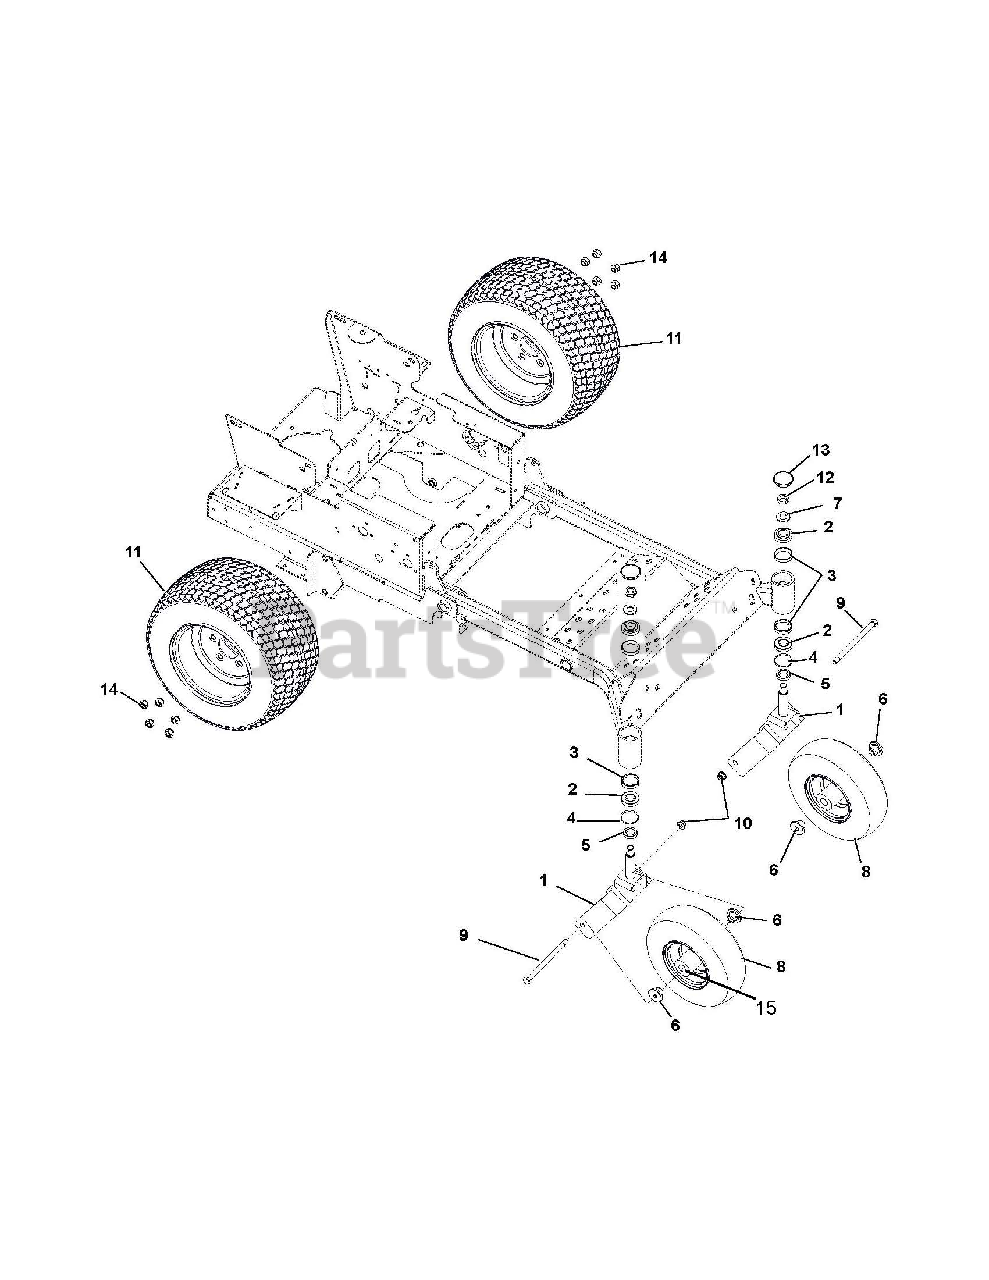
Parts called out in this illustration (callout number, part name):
1	Weldment, Front Fork
2	Bearing, Cone with Grease, 1.0 x .58
3	Bearing, Cup 1.980 x .420
4	Bearing Seal 1.5 x 2 x .18
5	Spacer, PM, 1.03 I.D. x 1.5 O.D. x .375
6	Spacer, Wheel
7	Washer, Flat, Steel .812 x 1.50 x .135
8	Tire/Wheel Assembly, 13 x 5.00-6
8	Tire/Wheel Assembly 4.80-8
9	Bolt, Hex .50-13 x 7.50 Grade 5
10	Nut, Nyloc Flange .50-13
11	Tire/Wheel Assembly, 20 x 10.00-10
11	Rim and Hub Assembly 4.10/3.50 x 6
12	Nut, Center Lock Jam .75-16
13	Cap, Dust
14	Wheel Nut .50-20
15	Bearing, 25MM ID x 52MM OD x 15MM
